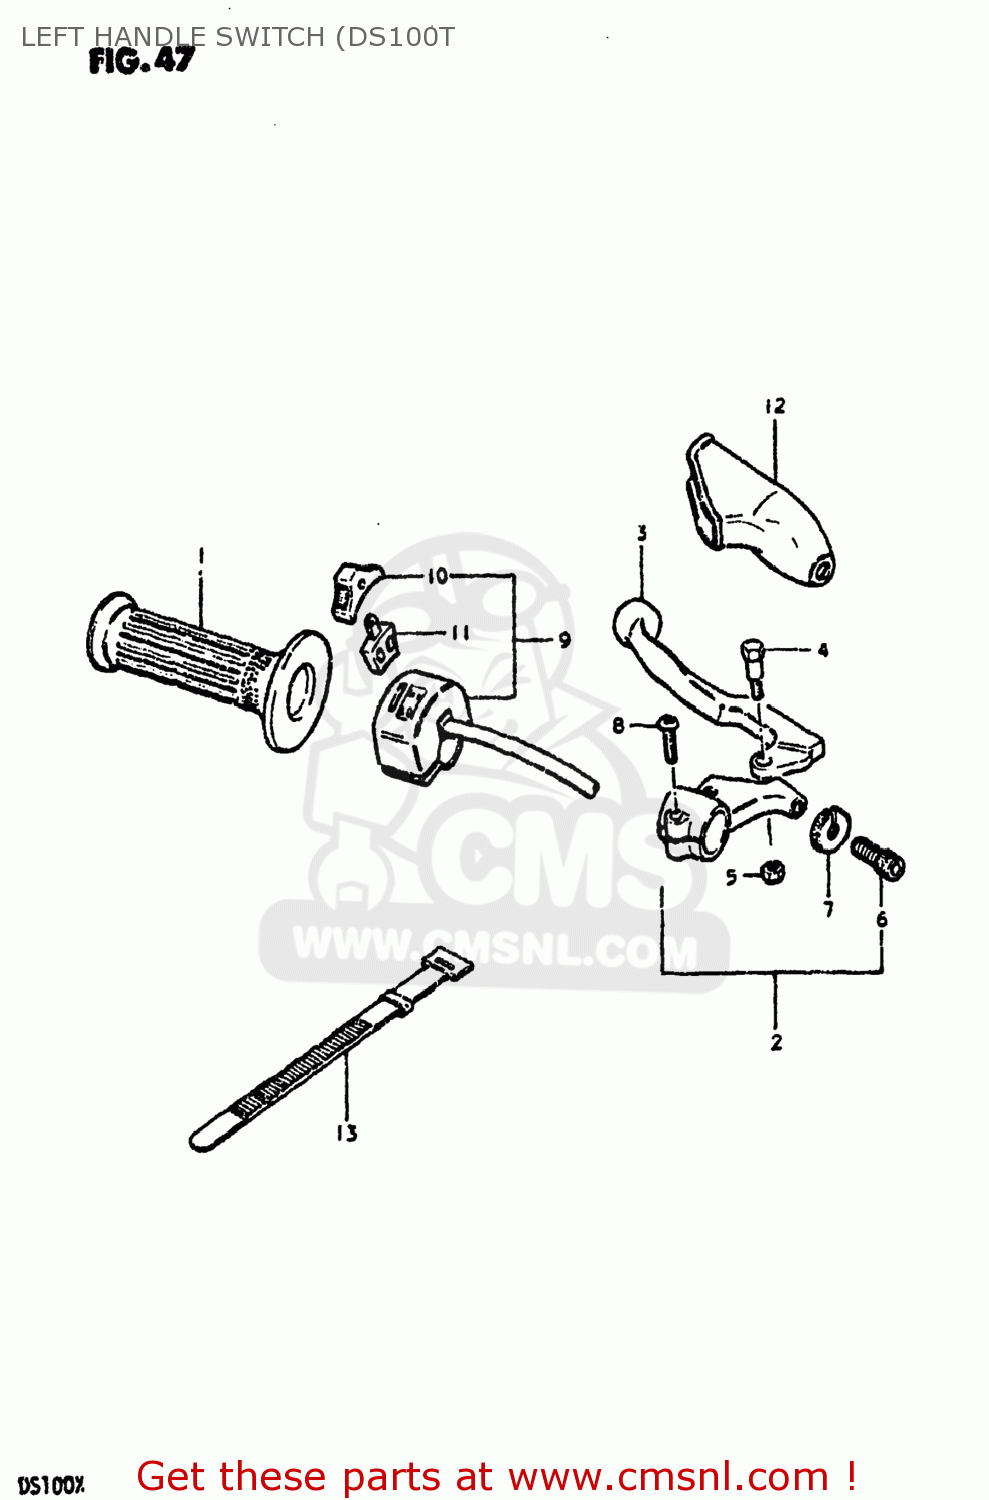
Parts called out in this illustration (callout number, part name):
1	GRIP,L
2	LEVER ASSEMBLY,CLUTCH
3	LEVER,CLUTCH
4	BOLT,LEVER
5	NUT 6MM
6	ADJUSTER,CABLE
7	NUT,CABLE ADJUSTER
8	SCREW
9	SWITCH,DIMMER
10	KNOB,LIGHTING & DIMMER
11	BLOCK,LIGHTING/DIMMER
12	COVER,CLUTCH LEVER
13	CLAMP(L:120)
